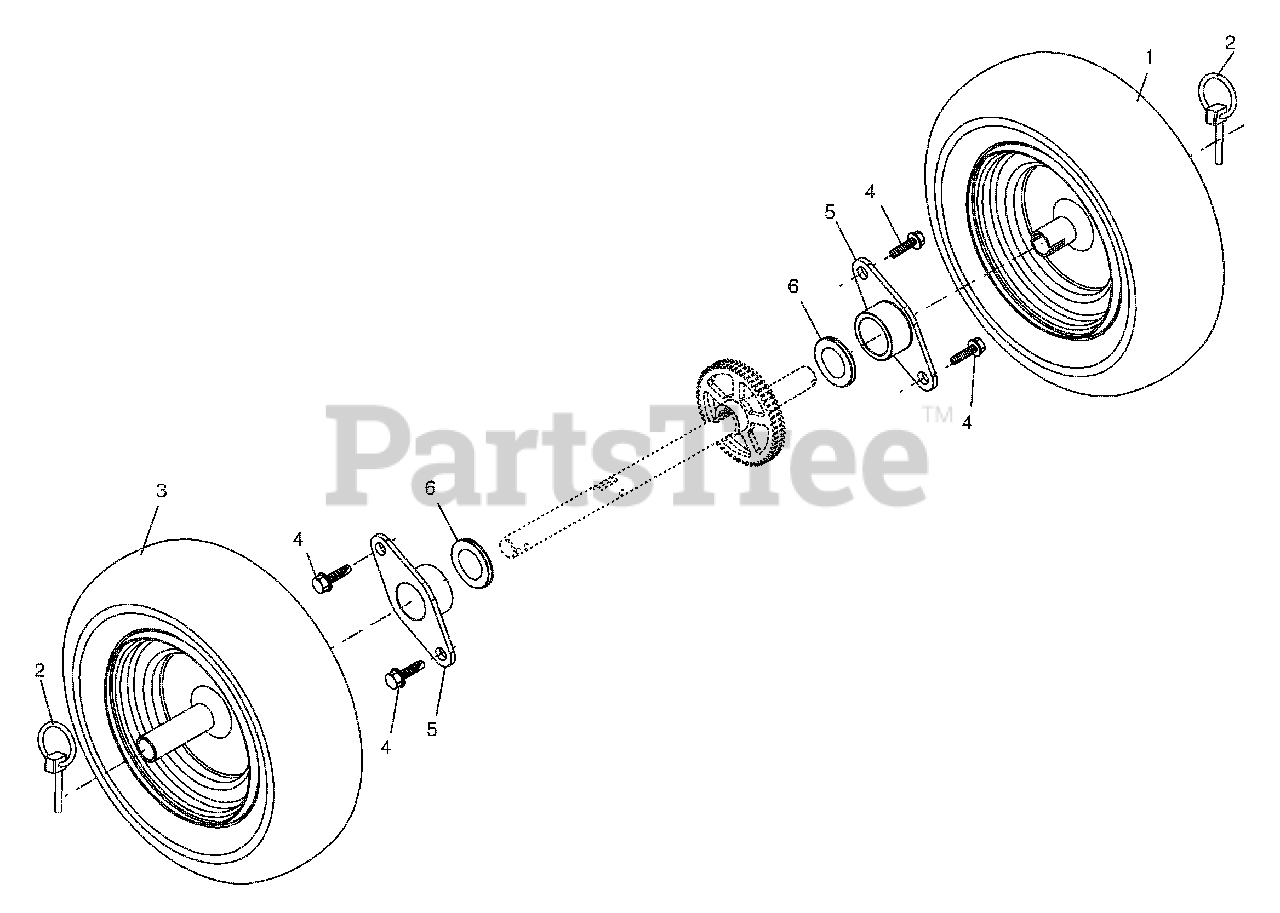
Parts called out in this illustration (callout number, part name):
1	Wheel Assembly, 16", LH
2	Pin, Klik 1/4
3	Wheel Assembly, 16", RH
4	Screw, Hex Head 5/16-18 x 1/2
5	Bearing, Axle
6	Washer, Thrust, 1"
